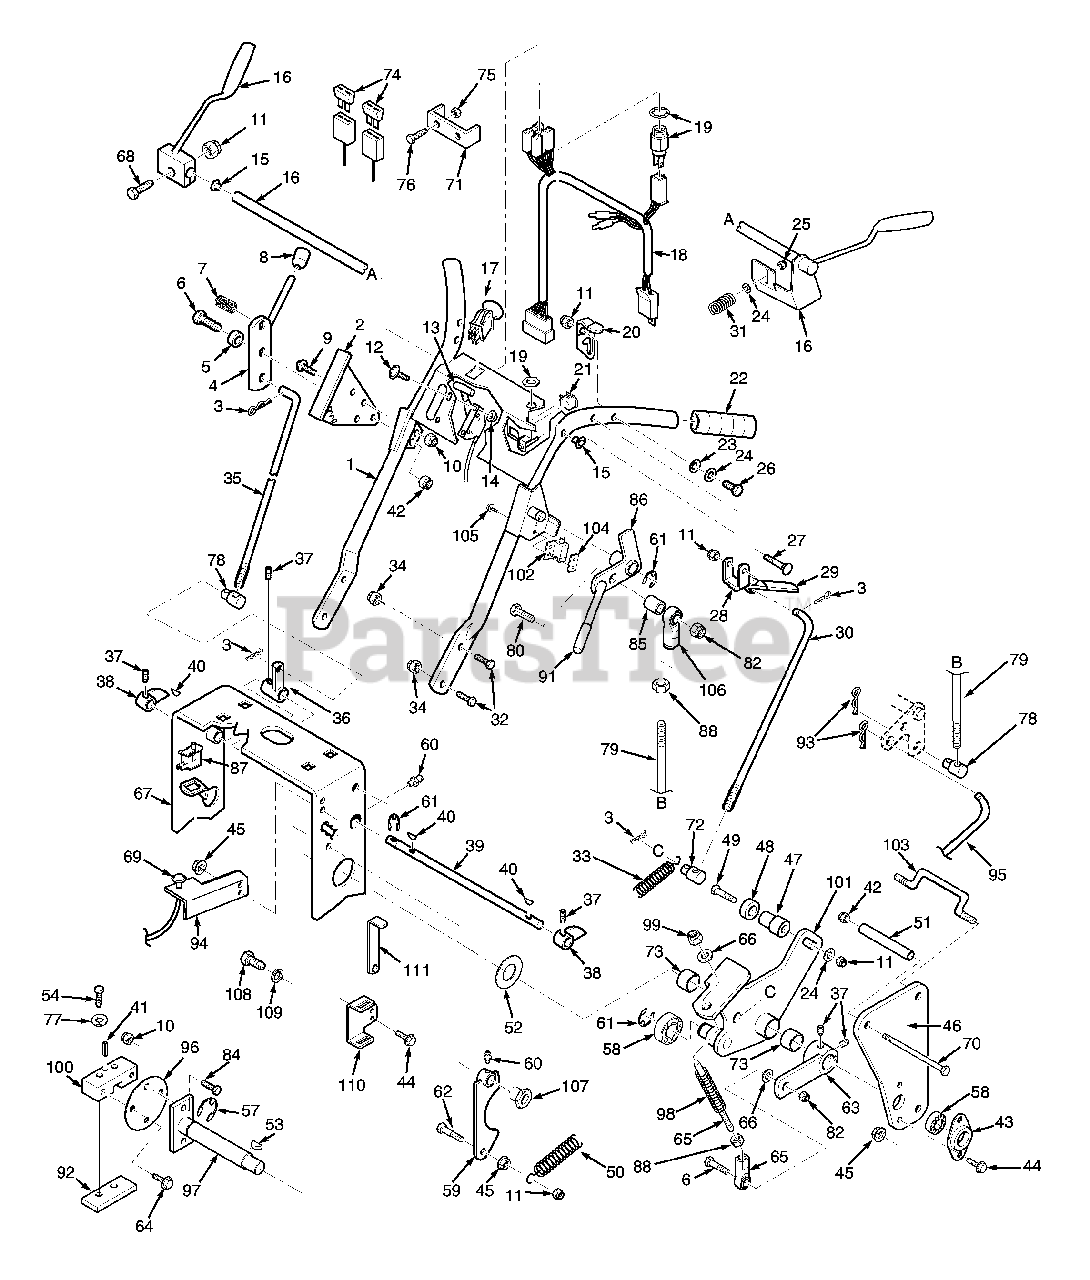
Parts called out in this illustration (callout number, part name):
1	Upper Handle Wlmt. W/Decals
2	Quadrant, Speed Control
3	Hairpin, .094 x 1.19
4	Lever, Speed Adjustment
5	Bushing, Speed Adjustment Lever
6	Hex Head Bolt, 3/8-16 x 1.5"
7	Ball Plunger
8	Knob, Speed Adjustment
9	Capscrew, 1/4-20 x 3/4" FHHS
10	Nut, 1/4-20 Elastic Stop
11	Nut, 5/16-18 Elastic Stop
12	Screw, #10-32 x 1/2" PW HD
13	Throttle Control
14	Nut, #10-32 Serr. Flange
15	Bushing
16	Handle, Oper. Presence-RH
16	Handle, Oper. Presence-LH
17	Switch,Elec.Clutch Eng.
18	Wire Harness, Manual Start
19	Key Switch, Manual Srt.
20	Neutral Latch-RH
21	Switch, Neutral Interlock
22	Grip
23	Washer, Curved Spring
24	Flat Washer
25	Nut, 5/16-18 Elastic Stop
26	Hex Head Bolt, 5/16-18 x 2"
27	Hex Hd. Bolt, 5/16-18 x 2.5"
28	Lever, Steering Control
29	Grip, Steering Control
30	Rod, Steering Control
31	Spring, Handle Return
32	Capscr., 3/8-16 x 1" Ser. Flange
33	Spring
34	Nut, 3/8-16 Serr. Flange
35	Rod Speed Control
36	Bellcrank, Speed Control
37	Setscrew, 1/4-28 x .25"
38	Cam, Speed Control
39	Jackshaft, Speed Control
40	Key, 1/8 x 1/2" Woodruff
41	Roll Pin, 3/16-.75
42	Nut, Elastic Stop 3/8-16
43	Flange, Bearing
44	Capscrew, 5/16-18 x 1" Serr. Flg.
45	Nut, 5/16-18 Serrated Flange
46	Plate, Side
47	Spacer, Neutral Bearing
48	Bearing, Speed Ctrl. Bellcrank
49	Hex Head Bolt, 5/16-18 x 1-3/4"
50	Spring, Return
51	Spacer, Side Plate
52	Flat Wshr., .766 x 1.25 x .035
53	Key, Woodruff, 3/16 x .75"
54	Bolt, Hex Head, 1/4-20 x 1.25
55	HH Bolt,5/16-18 x .75"
56	Lock Washer, 5/16
57	Clip, Retaining .750 diameter
58	Bearing, Ball Neutral Return
59	Cam, Neutral
60	Grease Fitting, 1/4-28 UNF
61	Retaining Ring, 5/8"
62	Hex Head Bolt, 5/16-18 x 1"
63	Lever, Speed Control
64	Bolt, Hex Head 1/4-20 x.75"
65	Linkage Assembly
66	Flat Wshr., 15/16 x .3906 x 12 ga
67	Deck, Engine 16" Wide
68	Hex Head Bolt, 5/16-18 x 1.25"
69	Choke Control
70	Bolt, Hex Head 3/8-16 x 4.25"
71	Fuse Holder
72	Swivel Joint, Steering Rod
73	Bushing
75	Nut, #10-32 Elastic Stop
76	Screw, #10-32 x 1.5" Phillips
77	Lockwasher, 1/4"
78	Swivel Joint
79	Rod, Brake Lever
80	Hex Hd. Bolt, 3/8-16 x 2.00"
81	Soc. Hd. Capscrew, #8-32 x .5"
82	Nut, 3/8-16 Elastic Stop
83	Washer #8-.170 x .375 x .032
84	Bolt, 1/4-20 x .75"
85	Spacer
86	Parking Brake Lever with Grip
87	Switch, Safety
88	Nut, 3/8-24
89	Bushing, Bearing Retainer
90	Bearing, Neutral Lock
91	Grip, Parking Brake
92	Plate, Threaded
93	Hairpin, .094 x 1.62"
94	Bracket, Choke Mtg.
95	Rod, Lower Brake
96	Plate, Coupler
97	Shaft, Pump Control
98	Spring
99	Nut, 3/8-16 Elastic Stop
100	Block, Pump Control
101	Control, LH
102	Switch, Parking Brake
103	Rod, Offset
104	Plate, Threaded
105	Screw #10-32 Sltd Hex Wshr Hd
106	Ball Joint, RH Thread
107	Bushing, Brake
108	Bolt, Hex Head 3/8-16 x 1"
109	Lockwasher, 3/8 Spring
110	Mounting Bracket, Wrench
111	Wrench
